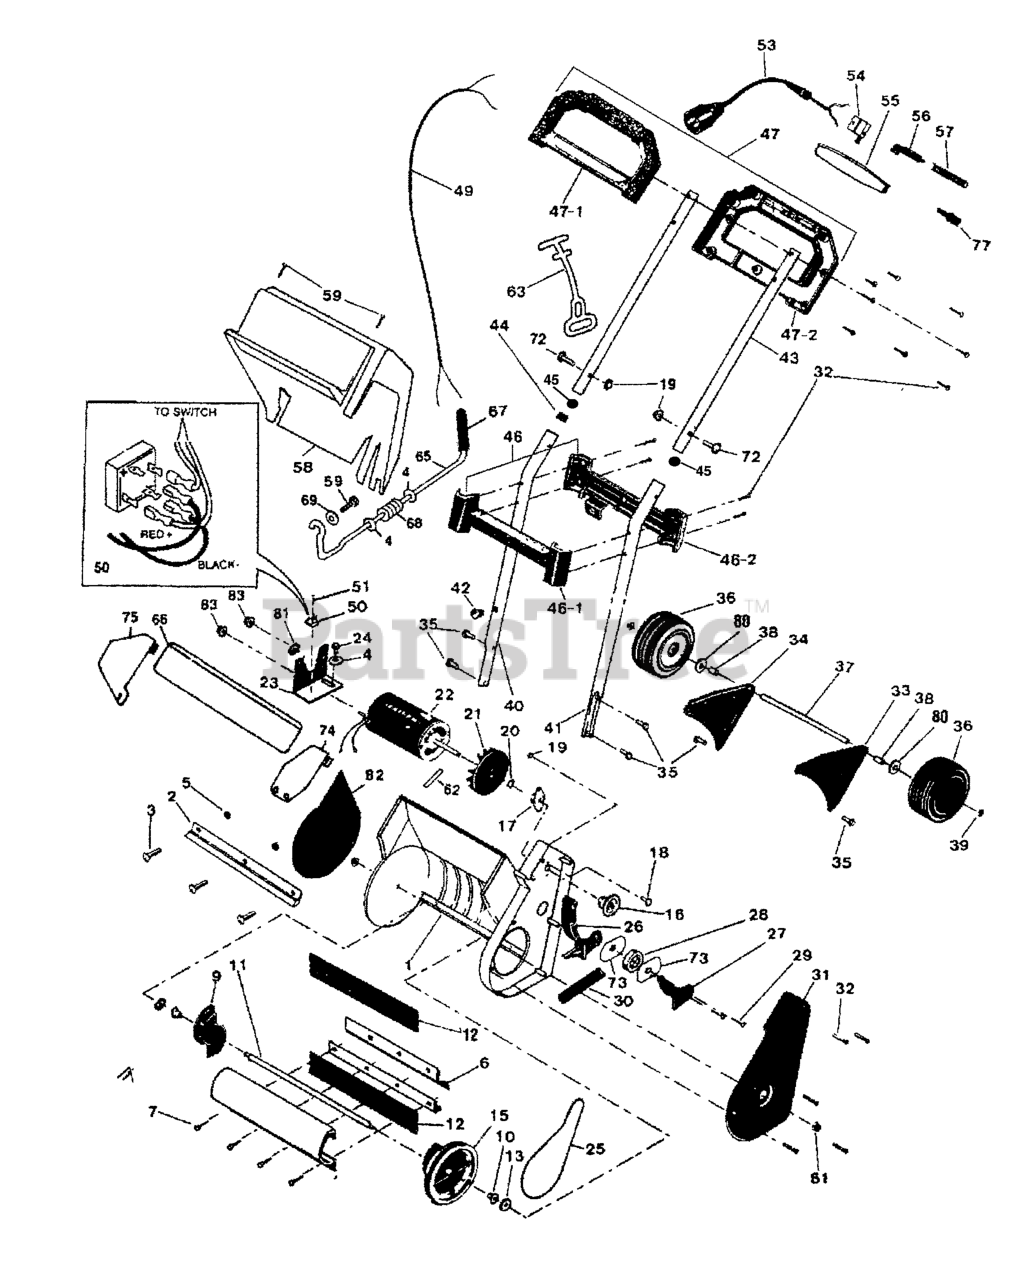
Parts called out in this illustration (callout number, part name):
1	HOUSING-SCOOP
2	BLADE, SCRAPER
3	BOLT, 1/4-20X .63 CARR
4	WASHER, FLAT .28X .63X.065
5	NUT, 1/4-20 WDFLWHIZ-LK
6	SEGMENT-DRUM
7	SCREW 10-24-3/4
9	CAP-DRUM END
10	BEARING-BRONZE
11	SHAFT-PADDLE
12	PADDLE-AUGER
13	WASHER, FLAT .328X .75
15	PULLEY-DRIVEN
16	PULLEY-DRIVE
17	BEARING, SELF ALIGN
18	SCREW, 1/4-20X .50
19	NUT, 1/4-20 HEXKEPS
20	RING, RET E .30X.04TRU5133-37
21	FAN,MOTOR
22	MOTOR, 120V
23	BRKT, MOTOR MT.
24	SCREW, 1/4-14X .75
25	BELT-DRIVE
26	ARM-IDLER
27	RETAINER IDLER BRNG
28	BEARING - BALL
29	SCREW, #8 X.63 POLY
30	SPRING IDLER
31	COVER-DRIVE HSNG LH
32	SCREW, #8 X 3/4 POLY
33	BRKT, WHEEL LH
34	BRKT, WHEEL RH
35	SCREW, 1/4-20X .63 WAHHTAP
36	WHEEL, 15" SNOW SHOVEL
37	AXLE WHEEL
38	SPACER-WHL,.328IDX.06X9/16L
39	NUT, PUSH ON CAP.312 OD
40	HANDLE, LOWER RH
41	HANDLE, LOWER LH
42	BUSHING
43	HANDLE, UPPER
44	PROTECTOR, HARNESS
45	HARNESS, PROTECTOR
46	SET,HANDLE.ASSIST
46-1	ORDER SET
46-2	ORDER SET
47	SET,HANDLE.GRIP
47-1	ORDER SET
47-2	ORDER SET
49	WIRE HARNESS
50	RECTIFIER, FULL WAVE
51	SCREW, #6 X .50
53	CONNECTIN LEAD
54	SWITCH, TRM 2516LOV
55	BAR-SWITCH
56	LEVER-SWITCH
57	SPRING - SWITCH
58	COVER-MOTOR
59	SCREW, 10-16X .63
61	NUT, 5/16-18 WDFLLK
62	PIN, GROOVED.125 DIAX.63LG
63	STRAIN RELIEF, CORD
65	ROD-DISCHARGE
66	SLIDER-VANE
67	GRIP, HAND VINYL
68	SPRING,ACTUATOR ROD NEW-15
69	WASHER, FLAT .750X .22X.070
72	BOLT, 1/4-20X1.25
73	RETAINER-BELT
74	OUTER DEFLECTOR
75	INNER DEFLECTOR
77	KEY, HI-PRO
80	WASHER, FLAT
81	GROMMETT.5 X .81 #GRO 1/2UL
82	COVER-HSNG RH
83	NUT, #10-32 HNYLLK
